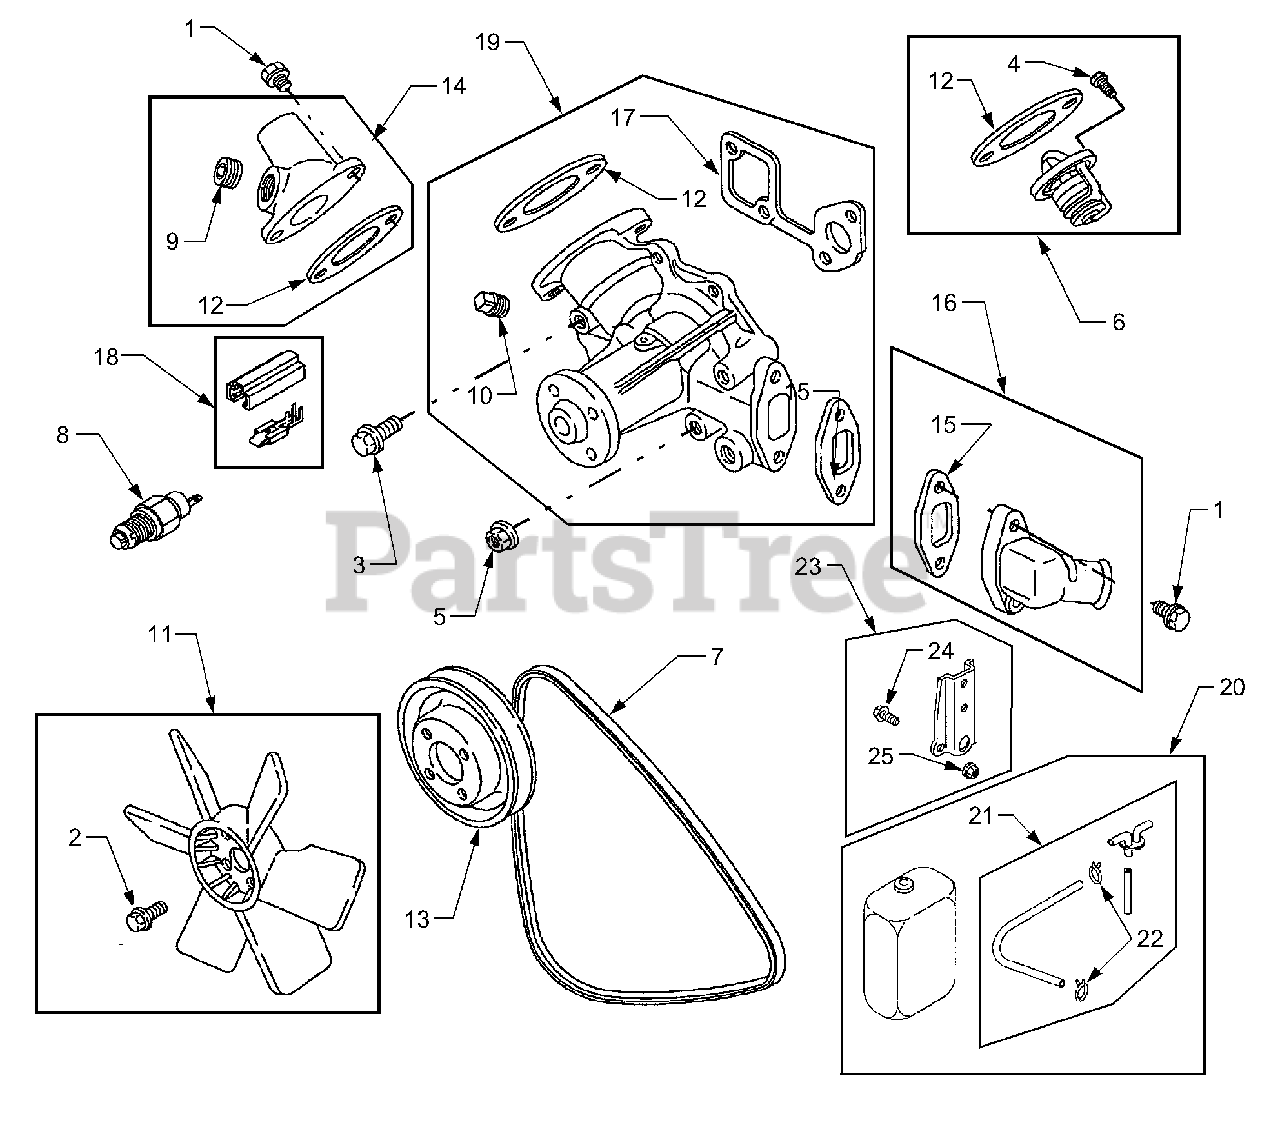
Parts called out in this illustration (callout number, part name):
1	Screw, Hex, 6mm
2	Screw, Hex,
3	Screw, Hex, 8mm
4	Screw, Metric
5	Nut, Hex Metric
6	Thermostat
7	Belt, V
8	Switch, Coolant Temperature
11	Fan, Radiator
12	Gasket, Outlet
13	Pulley, Pump
14	Housing, Outlet
15	Gasket, Inlet Housing
16	Housing, Inlet
17	Gasket, Water Pump
18	Connector, Coolant Temp. Switch
19	Pump, Water
20	Tank, Reserve
21	Cap, Reserve Tank
22	Clamp, Hose
23	Bracket, Reserve Tank Mtg.
24	Screw, Mtg. Bracket
25	Nut, Mtg. Bracket
